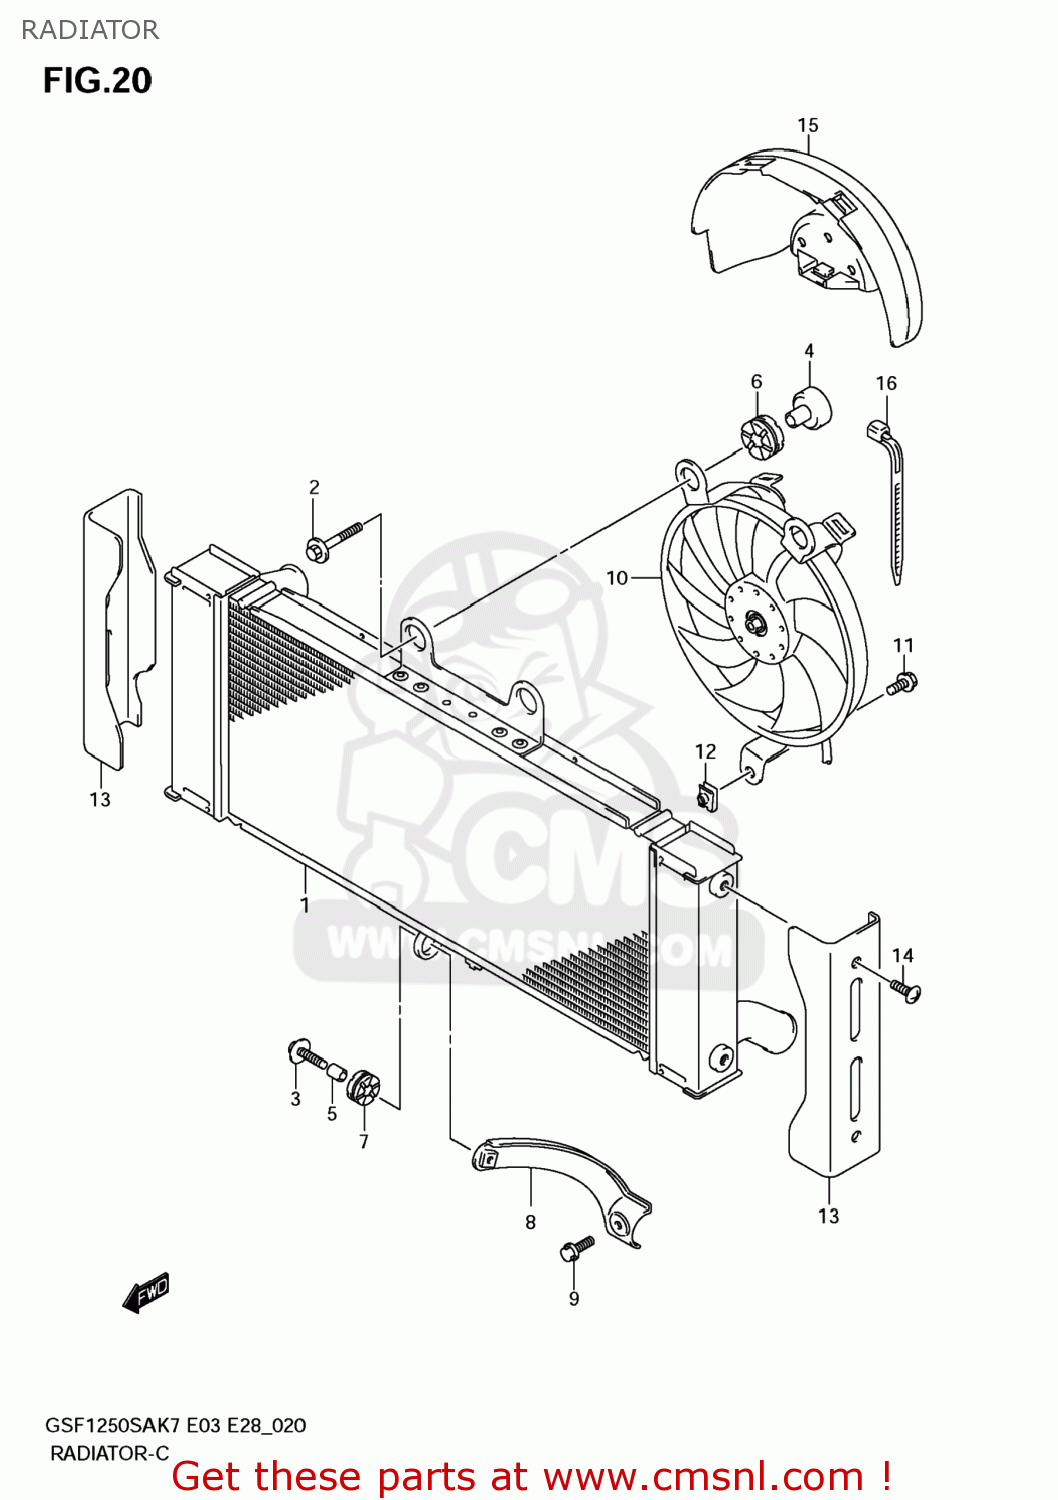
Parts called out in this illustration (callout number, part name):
1	RADIATOR ASSY,WATER
2	BOLT(6X37)
3	BOLT(6X25)
4	SPACER,RADIATOR UPR
5	SPACER(6.5X10X12)
6	CUSHION
7	CUSHION
8	BRACKET COMP,R
9	BOLT
10	FAN ASSY,RADIATOR
11	BOLT
12	NUT,RADIATOR FAN
13	COVER,RADIATOR
14	SCREW(6X12)
15	SHIELD,RADIATOR HEAT
16	CLAMP(L:125)
